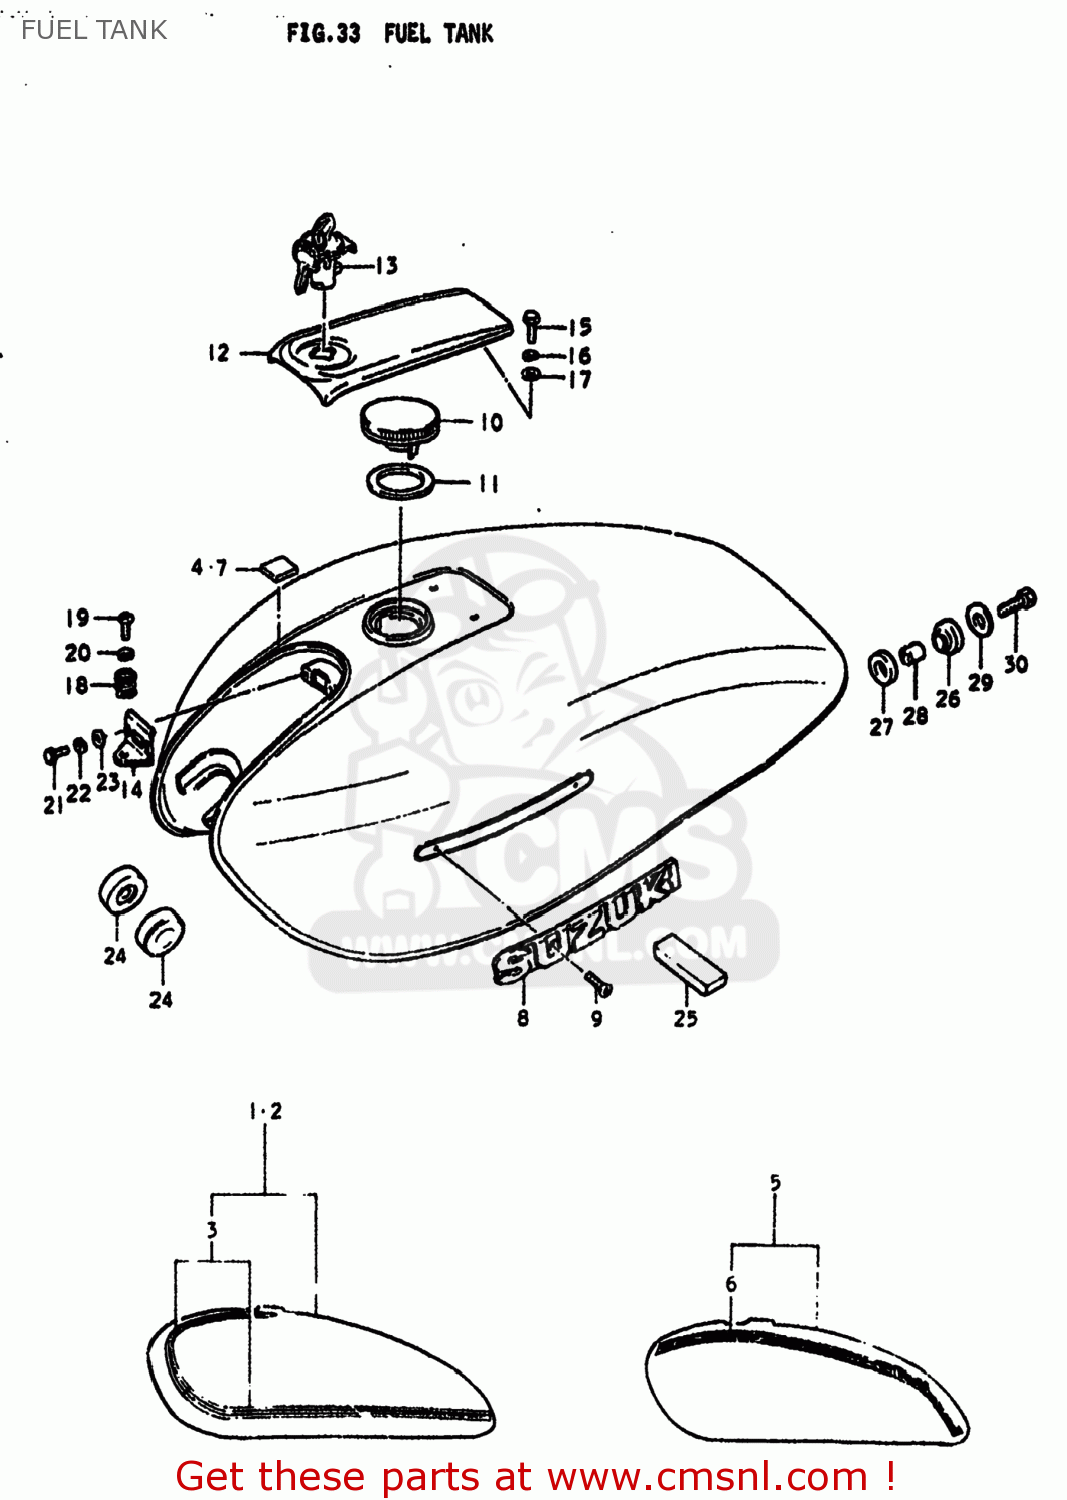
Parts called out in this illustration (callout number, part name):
1	TANK ASSEMBLY,FUEL
2	TANK ASSEMBLY,FUEL
4	CUSHION,FUEL TANK FR COVER
5	TANK ASSEMBLY,FUEL
7	CUSHION,FUEL TANK FR COVER
8	EMBLEM,FUEL TANK
9	SCREW 3X6
10	CAP,FUEL TANK
11	GASKET (NAS)
12	COVER,FUEL TANK
13	LOCK,FUEL TANK FR COVER
14	HOLDER,FUEL TANK FRONT COVER
15	BOLT
16	LOCK WASHER
17	WASHER
18	SPRING
19	SCREW
20	LOCK WASHER
21	BOLT
22	LOCK WASHER
23	WASHER
24	CUSHION
25	CUSHION
26	CUSHION
27	CUSHION
28	SPACER(8.5X12X19)
29	WASHER
30	BOLT
